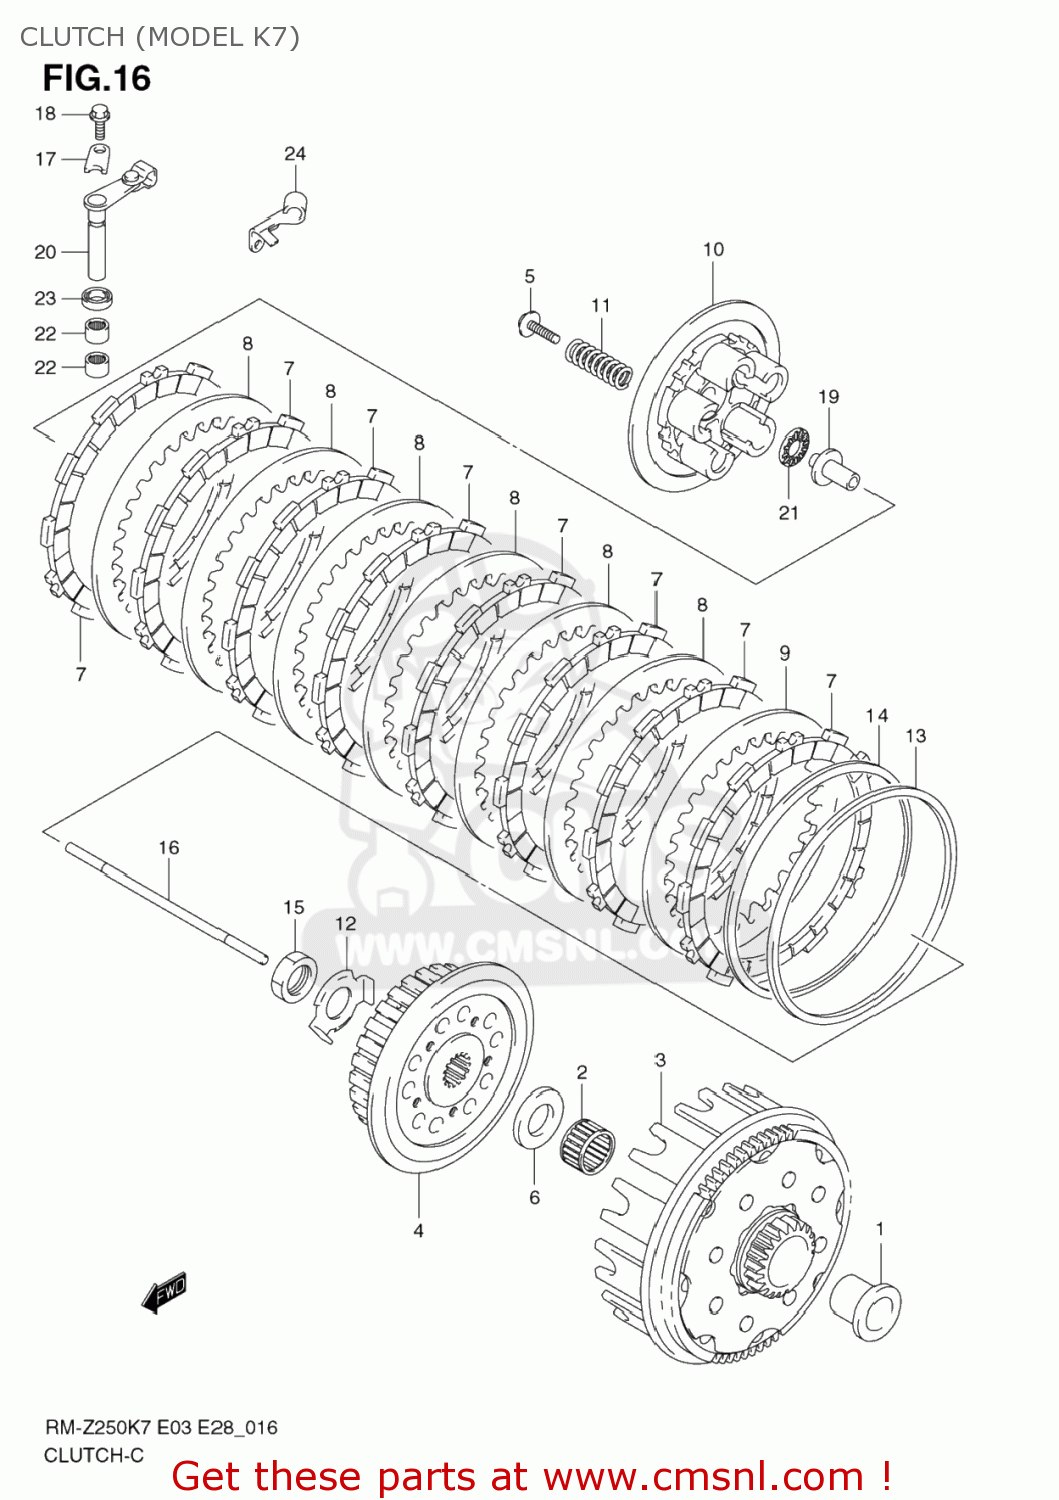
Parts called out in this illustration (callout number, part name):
1	SPACER,PRIMARY DRIVEN GEAR
2	BEARING(27X32X21.8)
3	GEAR ASSY,PRI DRIVEN
4	HUB,CLUTCH SLEEVE
5	BOLT,CLUTCH SPRING
6	WASHER(22X45X3)
7	PLATE,CLUTCH DRIVE (NAS)
8	PLATE,CLUTCH DRIVEN (NAS)
9	PLATE,CLUTCH DRIVEN (NAS)
10	DISC,CLUTCH PRESSURE
11	SPRING
12	WASHER,CLUTCH SLEEVE HUB LOCK
13	SEAT,CLUTCH PLATE WAVE WASHER
14	WASHER,CLUTCH PLATE
15	NUT
16	ROD,CLUTCH PUSH
17	RETAINER,CL RELEASE CAMSHAFT
18	BOLT(6X12)
19	PIECE,CLUTCH PUSH
20	CAMSHAFT,CLUTCH RELEASE
21	BEARING(10X22X2.8)
22	BEARING(10X14X10)
23	SEAL,OIL(10X17X5)
24	BRACKET,CLUTCH CABLE
